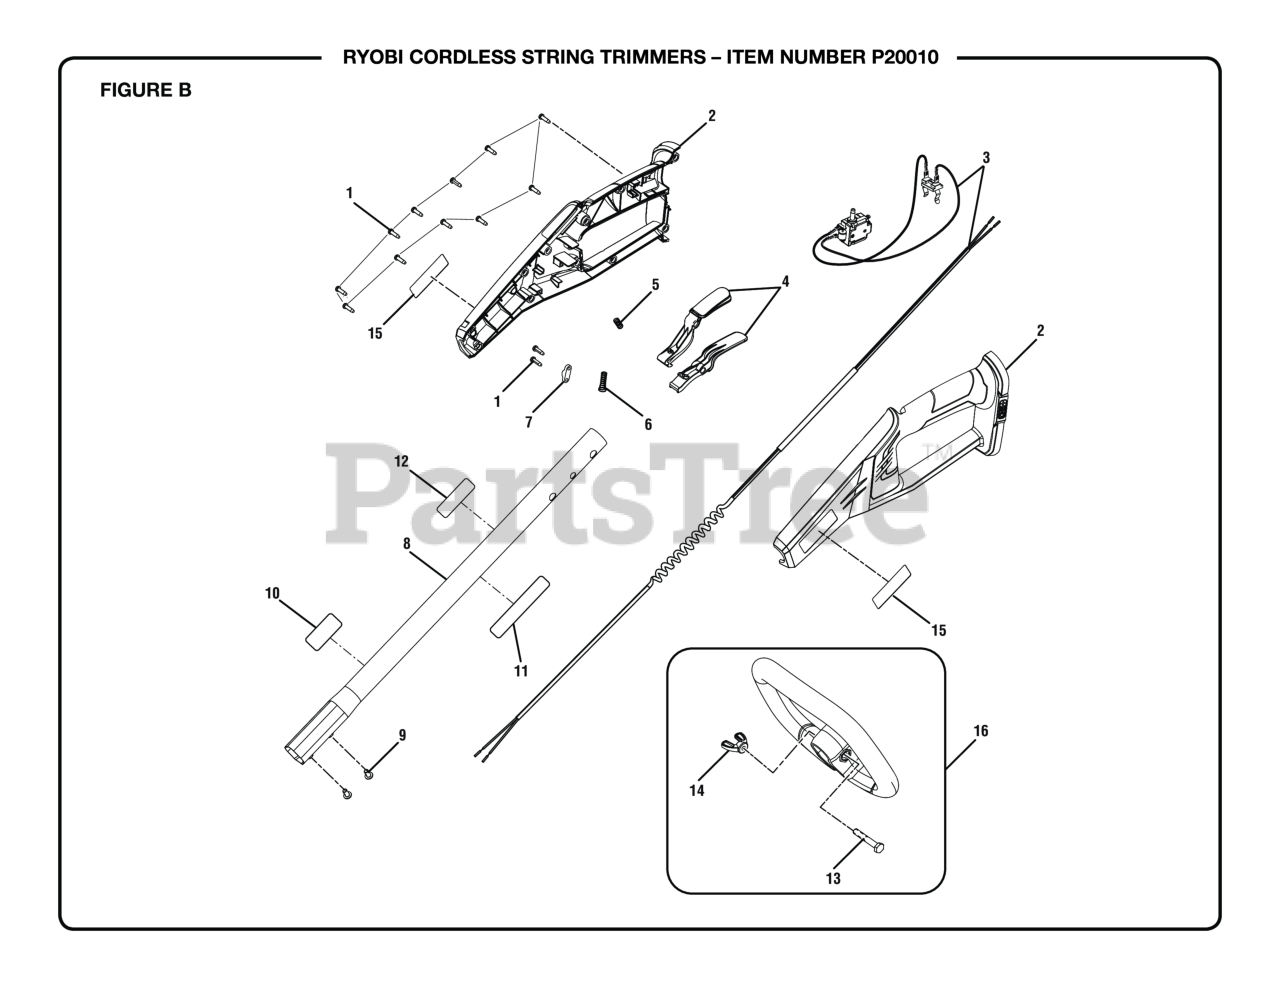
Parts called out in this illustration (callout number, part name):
1	Screw (M4 x 14 mm, T15 Torx Pan Hd.))
2	Handle Housing Assembly w/Label
3	Switch, Contact Plate Assembly and Wire Harness
4	Switch Trigger and Lock-Out Assembly
5	Compression Spring (Trigger Lock)
6	Compression Spring (Trigger)
7	Strain Relief Plate
8	Upper Tube Assembly
9	Screw w/Lock Washer (M5 x 8 mm, Pan Hd.)
10	Data Label
11	Warning Icon Label
12	Warning Label (Upper End)
13	Screw (1/4-20 x 40 mm, Cap Hex Hd.)
14	Wing Nut (1/4-20, Plastic)
15	Logo Label (Upper End)
16	Auxiliary Handle Assembly
